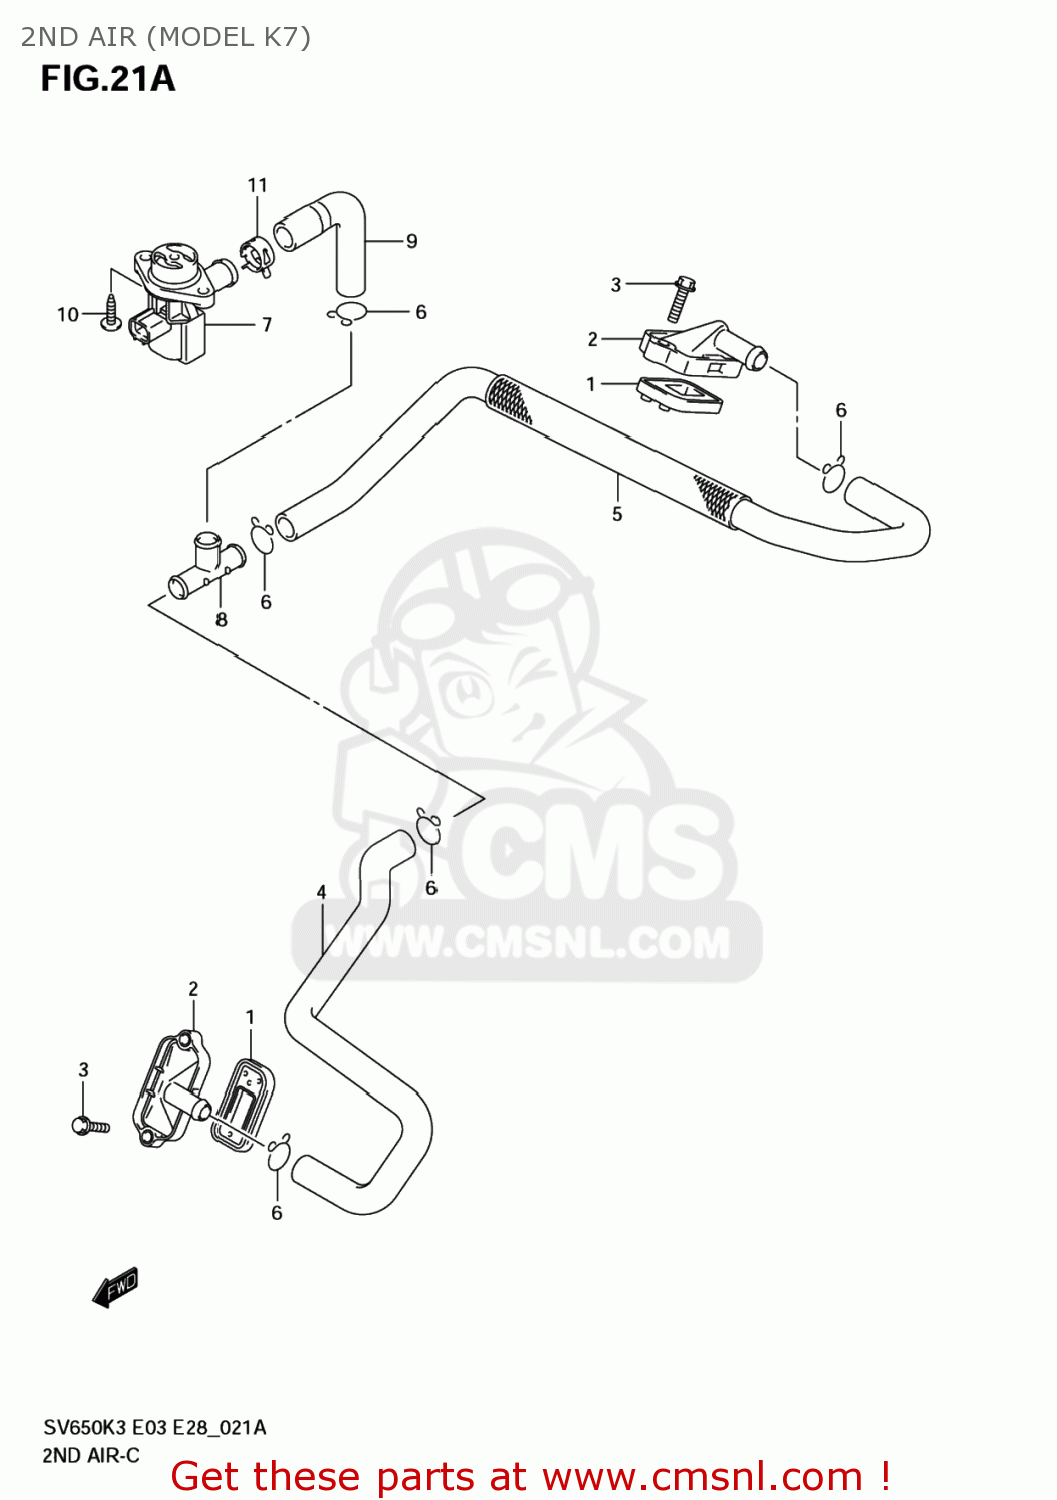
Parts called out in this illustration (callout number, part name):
1	VALVE ASSY,2ND AIR REED
2	COVER,2ND AIR
3	BOLT(6X20)
4	HOSE,2ND AIR VALVE FR
5	HOSE,2ND AIR VALVE RR
6	CLIP
7	VALVE ASSY,AIR CUT
8	JOINT
9	HOSE,2ND AIR VALVE
10	SCREW
11	CLAMP
